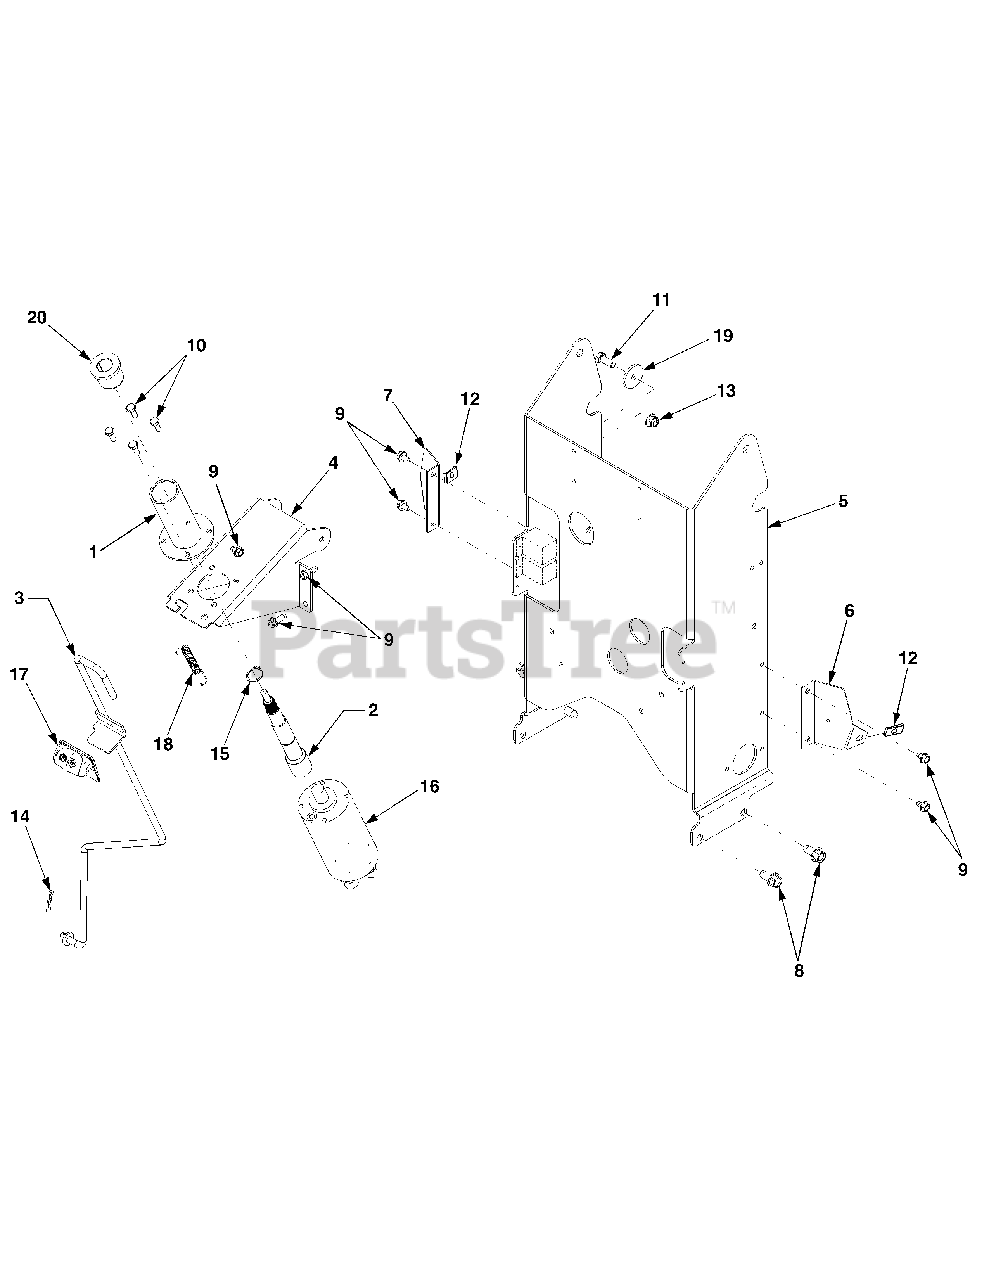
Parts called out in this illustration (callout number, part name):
3	Rod, Parking Brake
5	Pedestal
6	Bracket, Dash Mtg. RH
7	Bracket, Dash Mtg. LH
8	Screw, Hex Wash, Hd Tapp 3/8-16 x .75
9	Screw, Hex Wash, Hd Tapp 1/4-20 x .375
10	Screw, Hex, M6-1 x 16 Hardened
11	Screw, Hex Cap 5/16-18 x .75 GR5
12	Nut, Speed, 1/4-20
13	Nut, Hex Insert Flange Lock, 5/16-18 GrF
14	Pin, Internal Cotter
15	Ring, Snap, .75 Dia
16	Pump, Hydraulic Steering
17	Lever, Parking Brake
18	Spring, Extension
19	Washer, Flat, .33 x 1.25 x .12 .
20	Bearing, Flg, .75 ID x 1.25 OD
